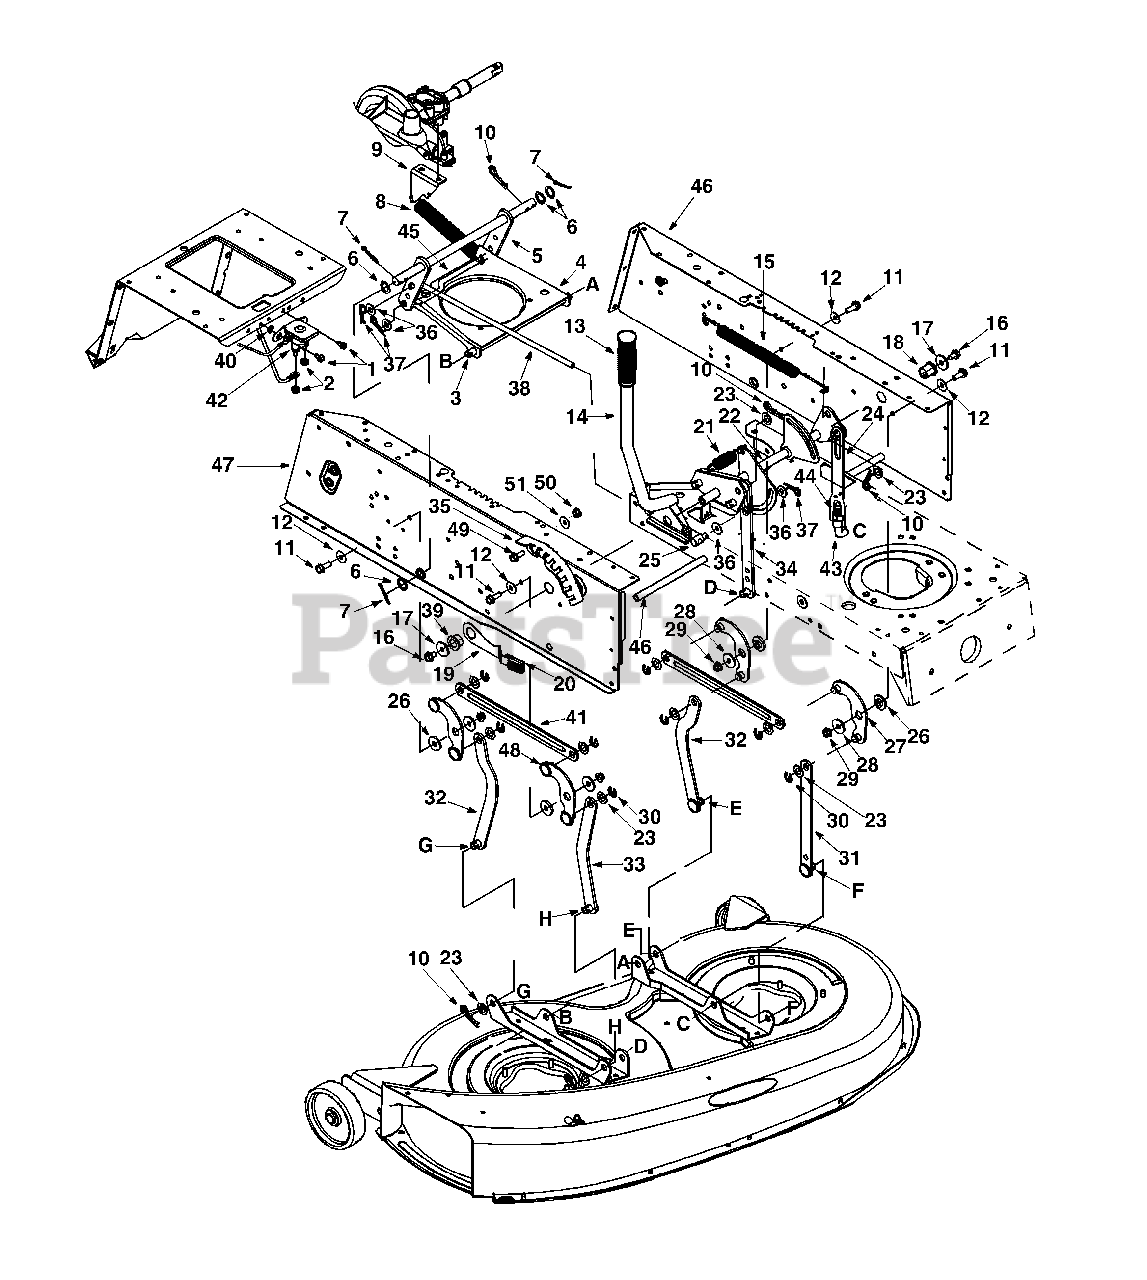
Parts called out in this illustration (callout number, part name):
1	Self Tap Screw 1/4-20 x .50" Lg.
2	Sems Hex Nut 1/4-20
3	Shaft 1/2" Dia. x 10.50" Lg.
6	Fl-Wash. .635 I.D. x .930 I.D.
7	Cotter Pin 1/8" Dia.
8	Extension Spring 7.58" Lg.
11	TT-Tap Scr. 5/16-18 x .75" Lg.
12	Bell-Wash. .325" I.D.
13	Grip (Lift Handle)
14	Deck Lift Handle Ass'y
15	Extension Spring
16	TT-Tap Scr. 5/16-18 x .625" Lg.
17	Fl-Wash. .344 I.D. x 1.25 O.D.
18	Flange Bearing .632 I.D.
19	Hgt. Adj. Stop Lever Ass'y
20	Knob
21	Extension Spring
25	Ferrule 3/8-24 x .375 Dia.
26	Shoulder Spacer .318" Dia.
27	Pivot Link Ass'y -L.H.
28	Fl-Wash. .344 I.D. x .125 O.D.
29	Flange L-Nut 5/16-18 Gr. 5
30	"E" Ring
31	Deck Hanger Link Ass'y
37	Hairpin Clip
38	Deck Belt Disengagement Rod
39	Flange Bearing .83 I.D. x .62 O.D.
42	Lift Link Adjuster
43	Hex Nut 1/2-20 Thd. (Gr. 5)
44	Shaft 3/8" Dia. x 9.34" Lg.
45	Running Board Rod
49	Hex Bolt 5/16-18 x .75" Lg.
50	Hex Nut 5/16-18 Thd.
51	Lock Washer 5/16" I.D.
